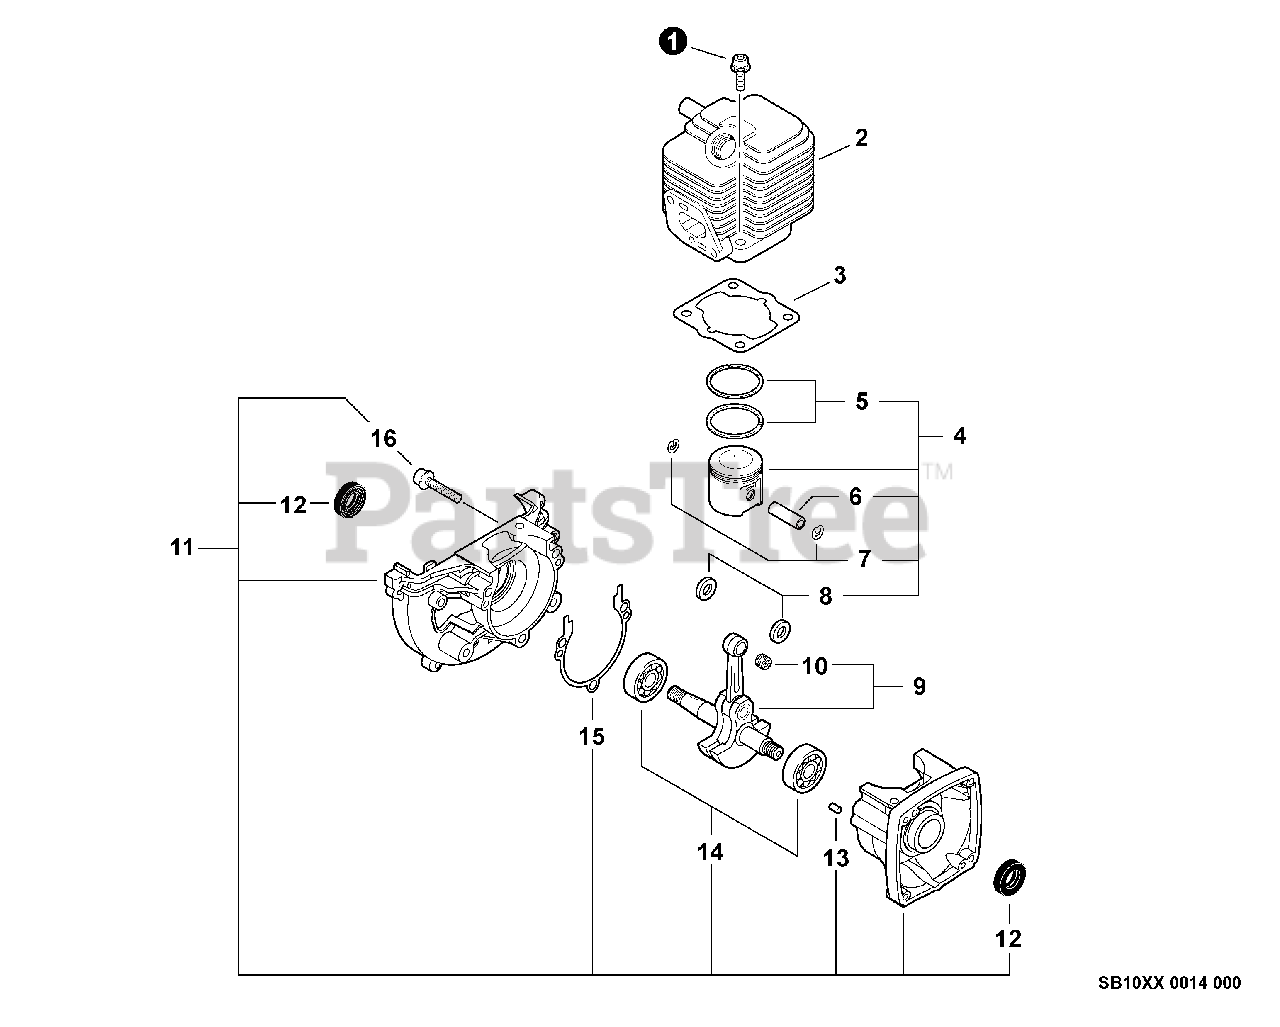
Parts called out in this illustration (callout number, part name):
1	SCREW - 5X22
2	CYLINDER
3	GASKET, CYLINDER
4	PISTON KIT
5	RING, PISTON
6	PIN, PISTON
7	RING, RETAINING
8	SPACER, PISTON
9	CRANKSHAFT ASSY
10	BEARING, NEEDLE - 8
11	CRANKCASE KIT
12	SEAL, OIL
13	PIN - LOCATING
14	BEARING, BALL - 6201
15	GASKET, CRANKCASE
16	SCREW - 5X28
